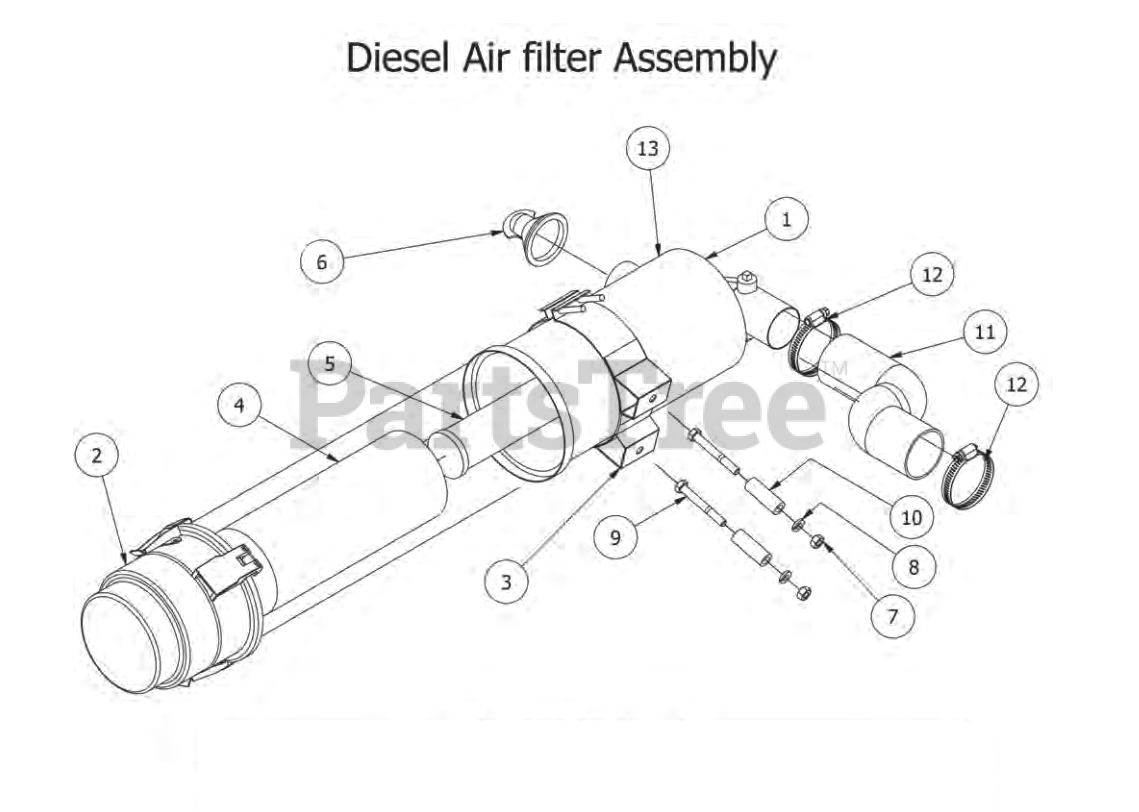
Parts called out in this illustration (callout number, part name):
1	Canister for All Diesel Models
2	Enginaire Air canister cap
3	Mounting Bracket For Diesel Air Filter
4	Diesel Air Filter- Outer
5	Diesel Air Filter- Inner
6	Debris Plug-Enginaire Filter
8	5/16" Lock Washer
9	5/16" x 2 1/2" Bolt
10	.378 x .625x 1.750 Spacer Zinc
11	Air Intake Hose-Diesel Air Filter Canister
12	2-1/2" Hose Clamp
13	Enginaire Canister VLR-Complete Assembly
